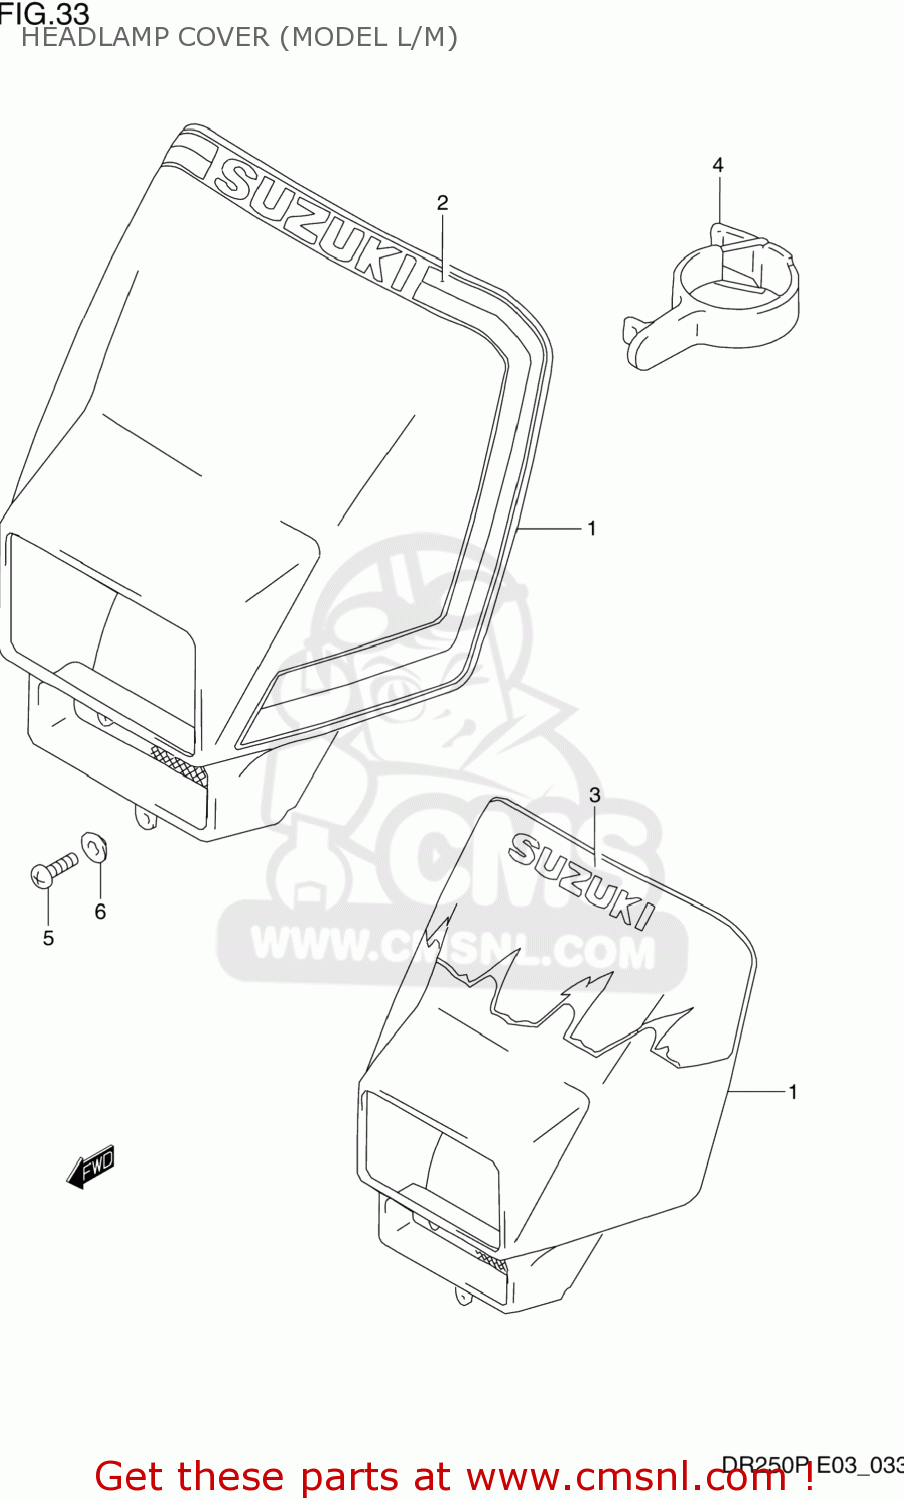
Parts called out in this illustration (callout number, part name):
1	COVER,HEADLAMP
2	TAPE,HEADLAMP COVER
3	TAPE,HEADLAMP COVER
4	BAND,HEADLAMP COVER
5	SCREW(5X12)
6	WASHER
